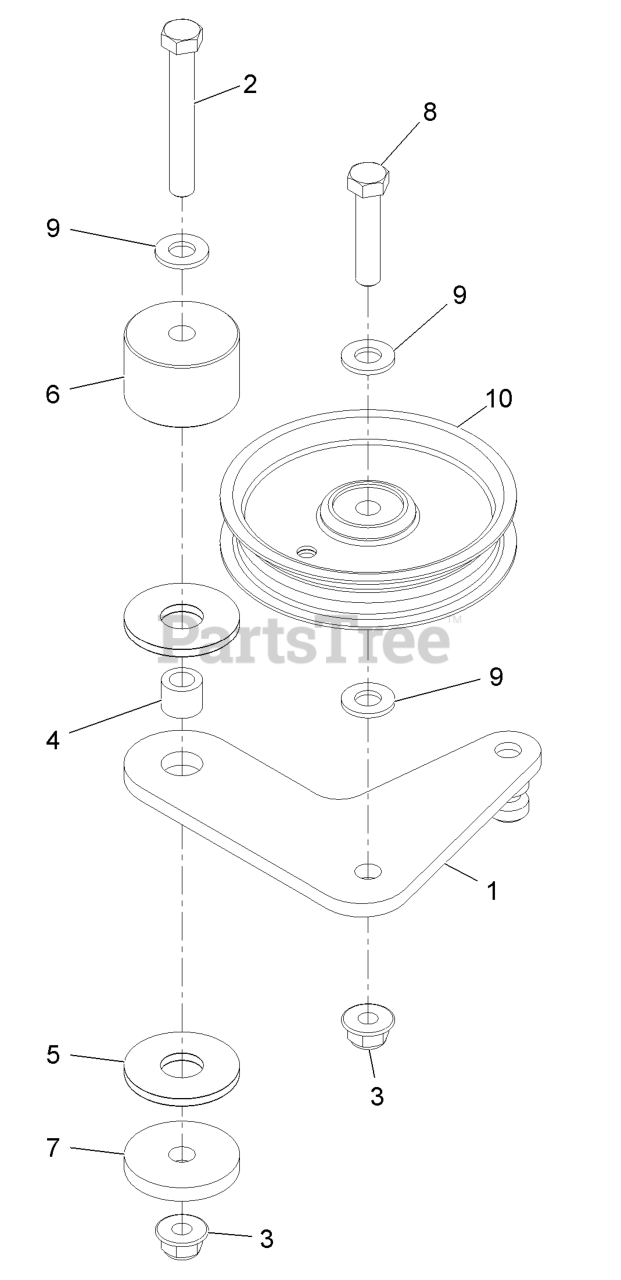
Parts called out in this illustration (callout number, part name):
1	PLATE-IDLER
2	SCREW-HH
3	NUT-HF, NI
4	BUSHING-LEVER, LIFT
5	WASHER-FRICTION, COMPOSIT
6	HUB-IDLER
7	WASHER-PLAIN
8	SCREW-HH
9	WASHER-FLAT
10	PULLEY-IDLER
